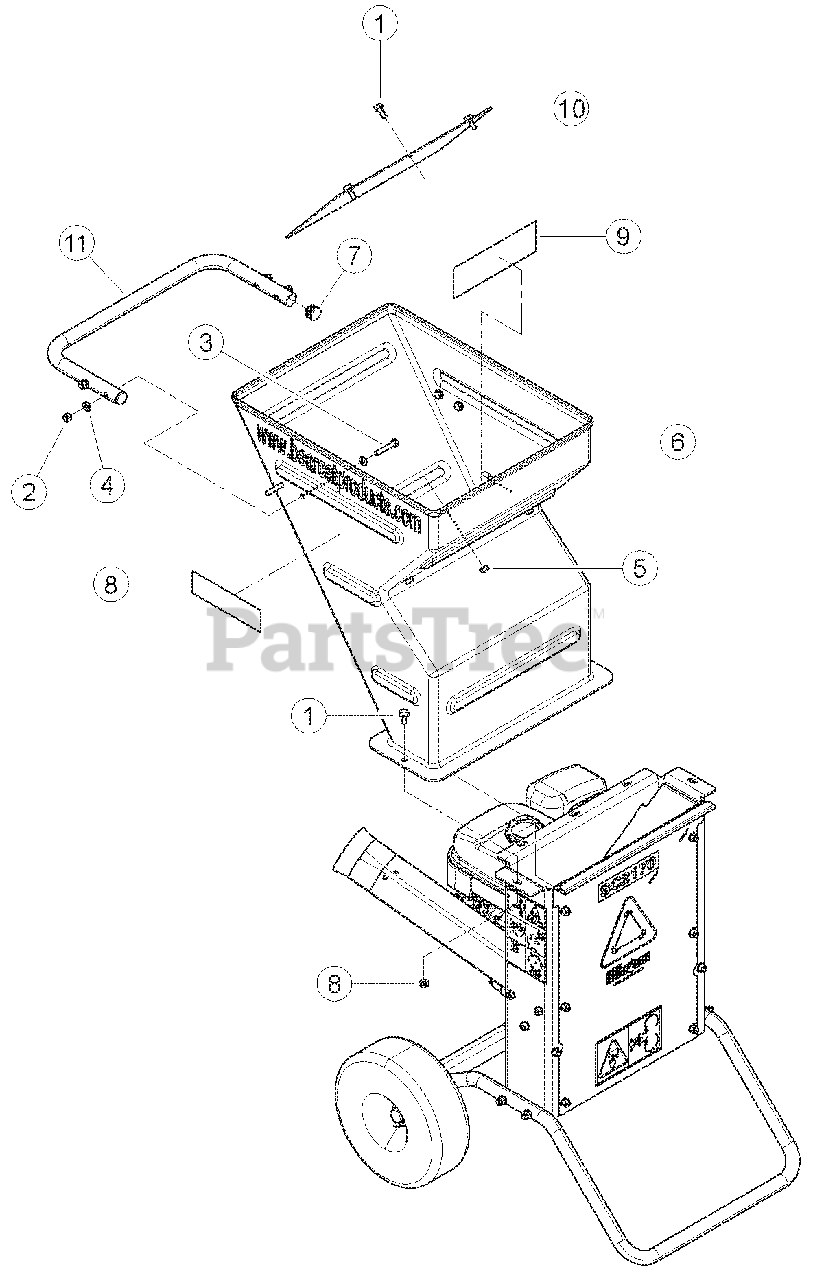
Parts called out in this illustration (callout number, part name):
1	BOLT, 5/16 X 3/4 SERR FLANGE GR5 ZP
2	NUT, 5/16 NE NYLOCK ZP
3	BOLT, 5/16-18 X 1-3/4 HEX HD GR5 ZP
4	WASHER, 5/16 SAE FLAT ZP
5	NUT, 5/16 SPIRAL LOCK
6	HOPPER, 2 INCH SHREDDER/CHIPPER
7	PLUG, 1" ROUND RIBBED
8	DECAL, ECHO BEARCAT 6.82 X 1.90 (WHITE)
9	DECAL, MANUAL INFORMATION
10	FLAP, SHREDDER HOPPER
11	HANDLE, SC2170
